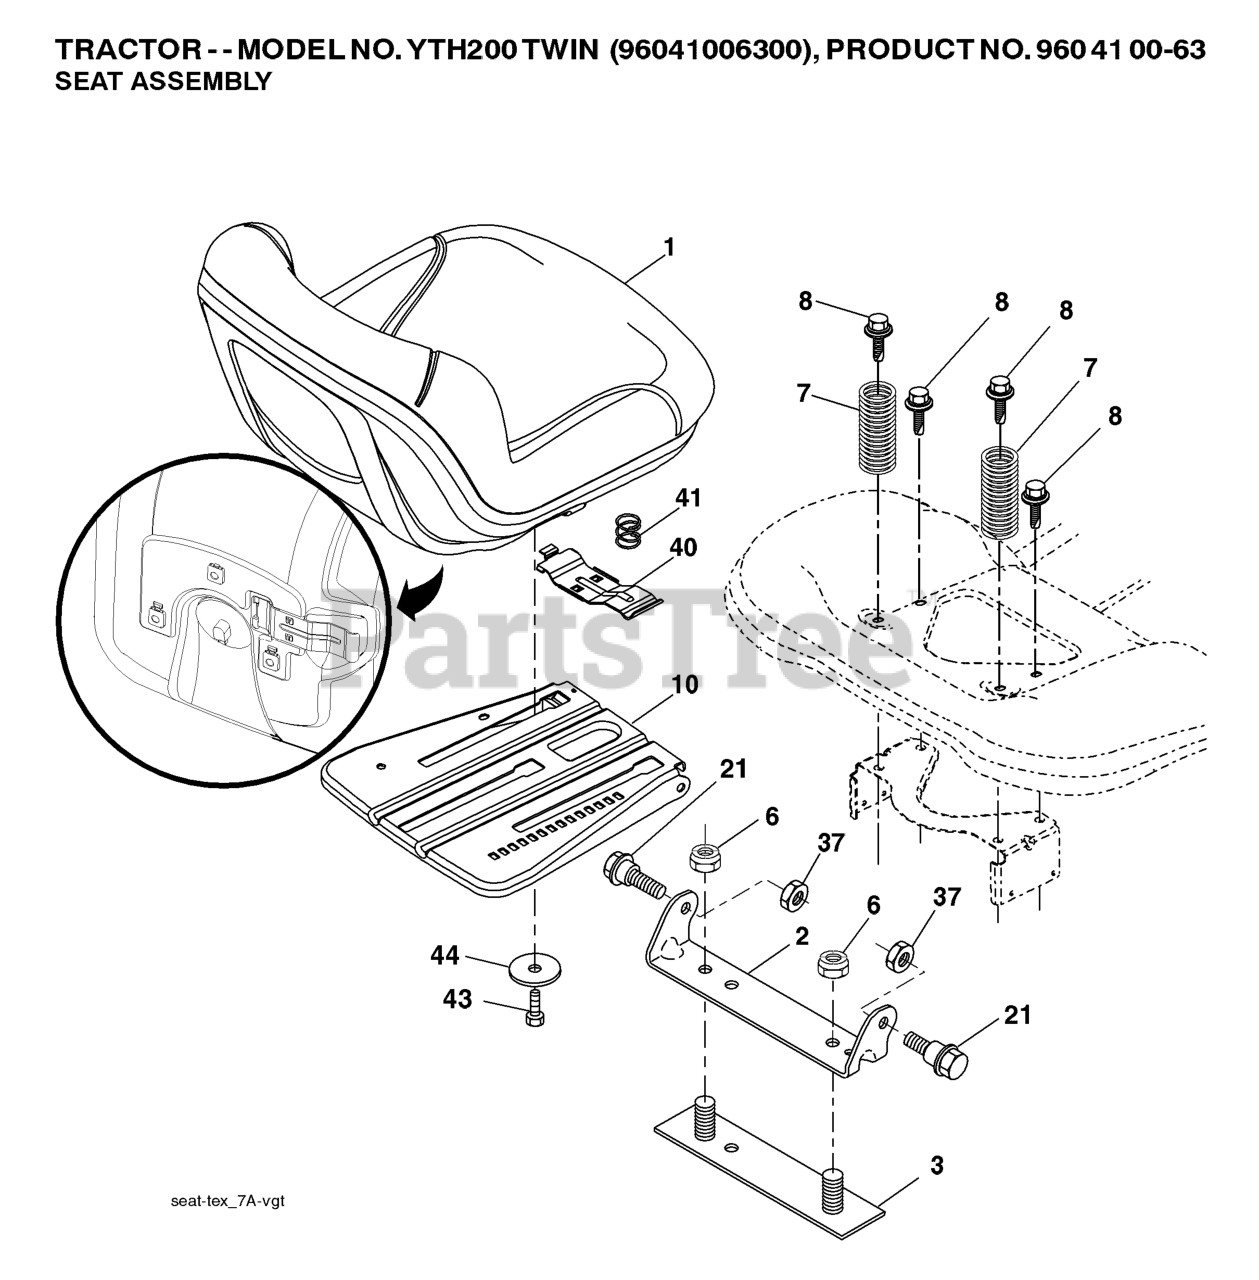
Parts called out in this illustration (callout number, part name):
1	SEAT - GREY
2	BRKT.PIVOT.FENDER
3	STRAP
6	NUT
7	SPRING COMPRESSION
8	BOLT.5/16-18UNCX3/4 W/SEMS.BLK
10	PAN.ASM.SEAT.3PT
21	BOLT.SHOULDER.5/16-18
37	NUT.71038.31-18.HEX.NYLOCK
40	HANDLE.SLIDE.SEAT.TEX.BLACK
41	SPRING.LATCH.SEAT.TEX
44	WASHER 13/32 X 2-3/8 X 12GA
